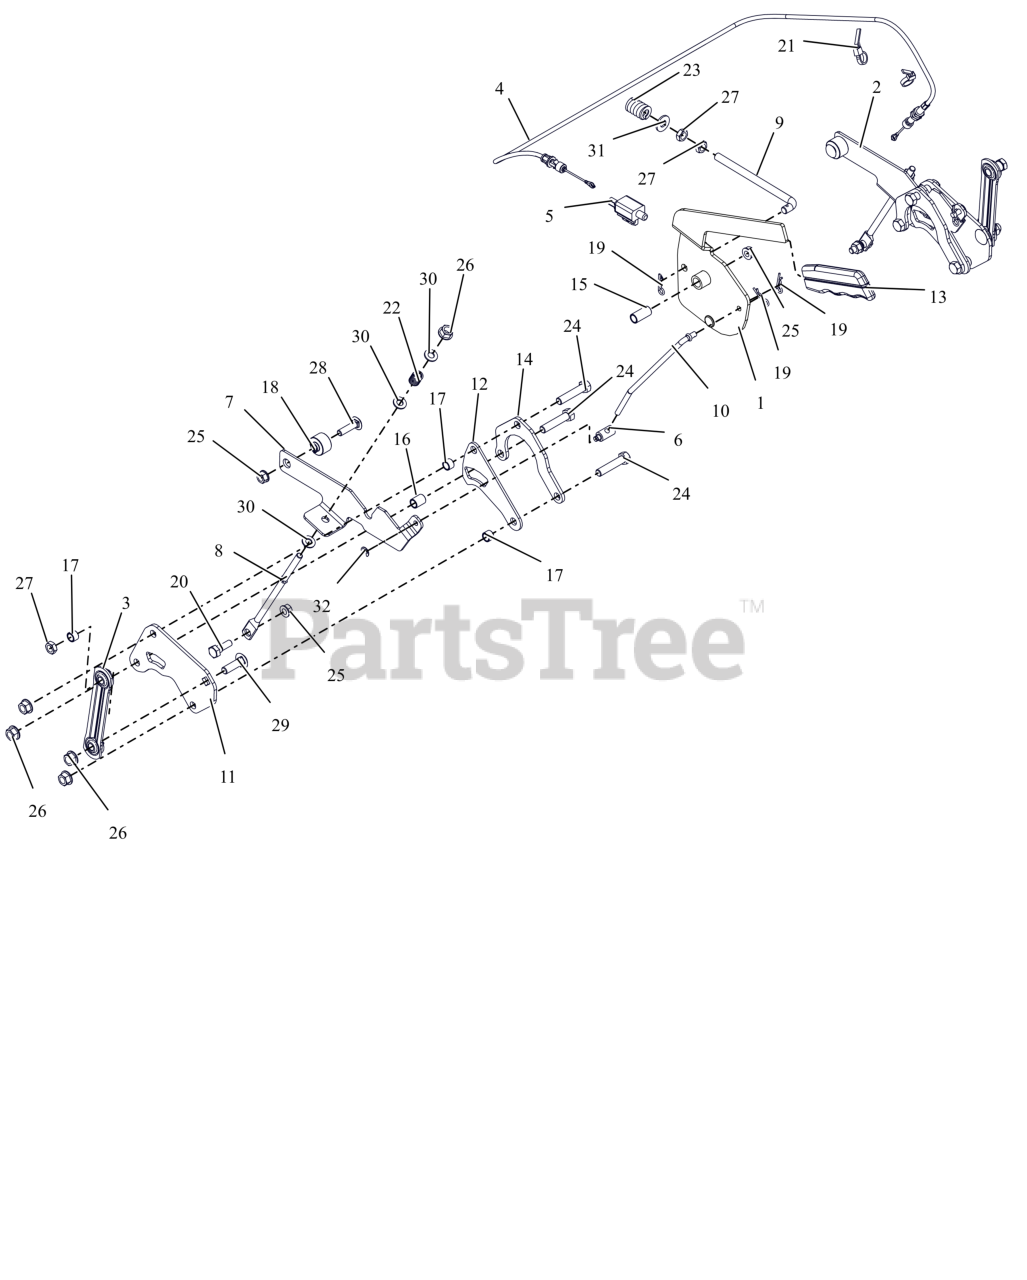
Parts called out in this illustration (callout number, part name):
1	LEVER, PARKING BRAKE
2	ARM, BRAKE - LH (W/PIN)
3	LINK, STAMPED STEERING
4	CABLE, BRAKE
5	SWITCH, SINGLE POLE N.O.
6	TRUNION, 1/4-20
7	ARM, BRAKE-RH
8	ROD, LINK - TRANSMISSION BRAKE
9	ROD, OVER CENTER
10	ROD, BRAKE LINK
11	BRKT, TRANSAXLE STEERING
12	BRKT-SPACER
13	GRIP, PARKING BRAKE (YELLOW)
14	PLATE, REAR REINFORCING
15	BSHG-SLV .385X.500X1.045
16	SPCR, SLV .385X.500X.652
17	SPCR, SLV .385X.500X.350
18	SPCR, FLANGE
19	PIN, HAIR #213 .08X1.19 ZCC
20	BOLT,SHLDR .38X.25 -.31-18X.75
21	CABLE TIE LG 5-1/2
22	SPRING, COMPRESSION
23	SG-COMP .187X.56X1.62
24	BLT, HEX .38-16X1.75 G5 ZCC
25	NUT-LK-TOP-FLG .312-18 GF ZCC
26	NUT-LK-TOP-FLG .38-16 ZC120
27	NUT-JAM .375-16 G2 ZCC
28	BLT, RHSSN.31-18X1.25 G5 ZCC
29	BLT,RHSSN .38-16X1.25 G5 ZCC
30	WSHR,FLT .344X.688X.065 ZCC
31	WSHR,FLT .375X.875X.083 ZCC
32	RG-RTNG-EXT .250X.025
